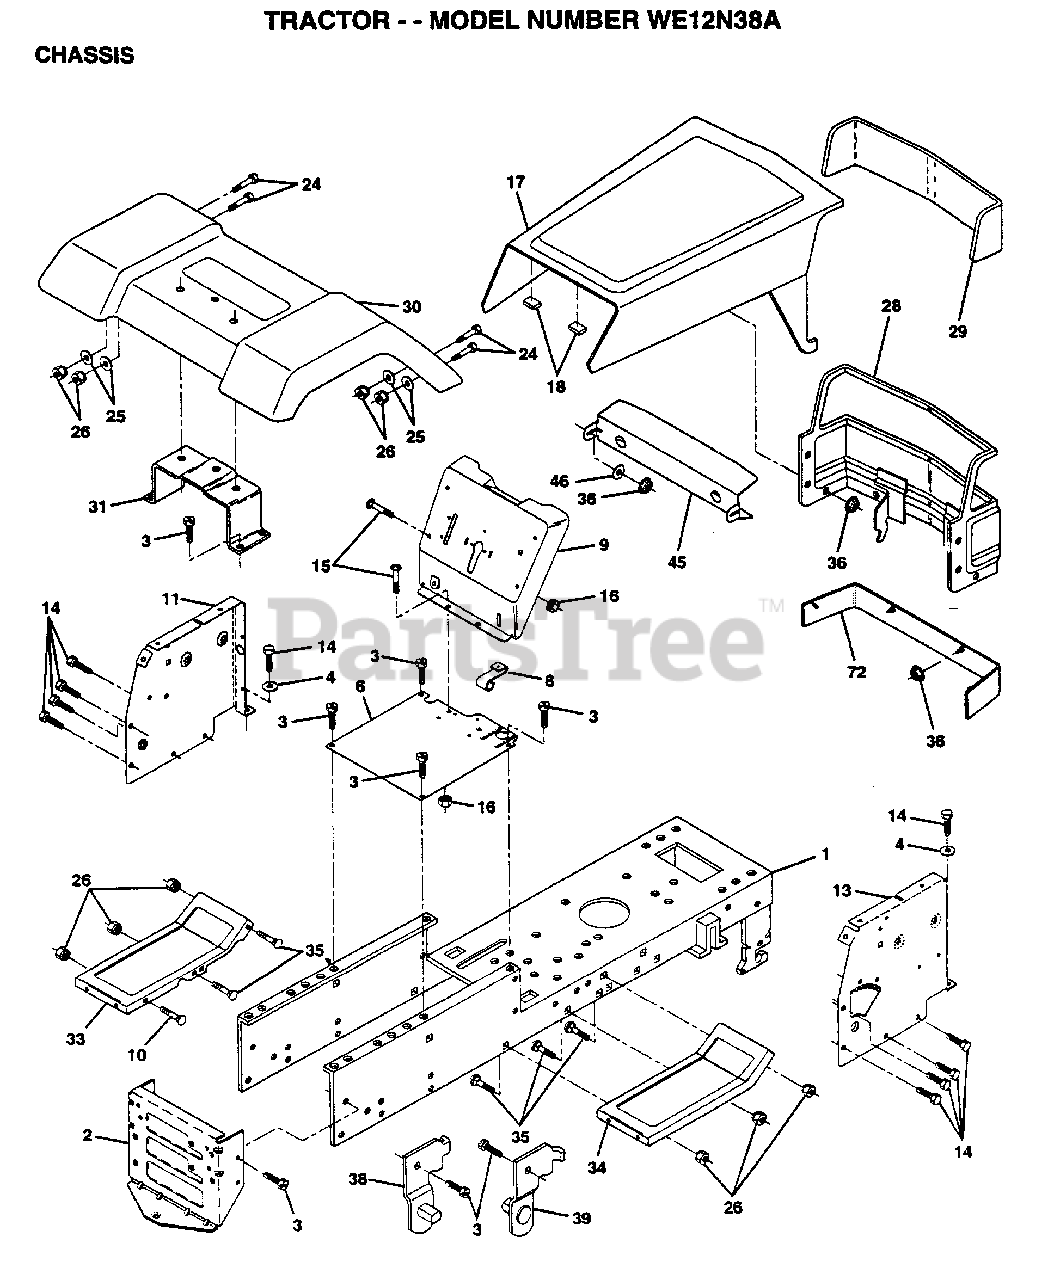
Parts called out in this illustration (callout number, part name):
1	CHASSIS.WLD.11GA
3	SCREW
4	WASHER
8	"CLIP,INSULATOR"
9	DASH SILKSCRN 1
11	DASH PANEL LH
14	SCREW LT
15	SCREW
17	HOOD.W/SD.PNLS.LT
24	BOLT
25	WASHER
28	GRILLE.RALLY.BAR.
29	LENS SERVICE KIT
31	BRKT FENDER
33	FOOTREST.LH.PERF.
34	FOOTREST.RH.PERF.
35	BOLT
36	PAL NUT LT
38	BRACKET ASM LH
39	BRACKET ASM RH
46	RETAINER
72	STRAP.GRILLE.PNT.
